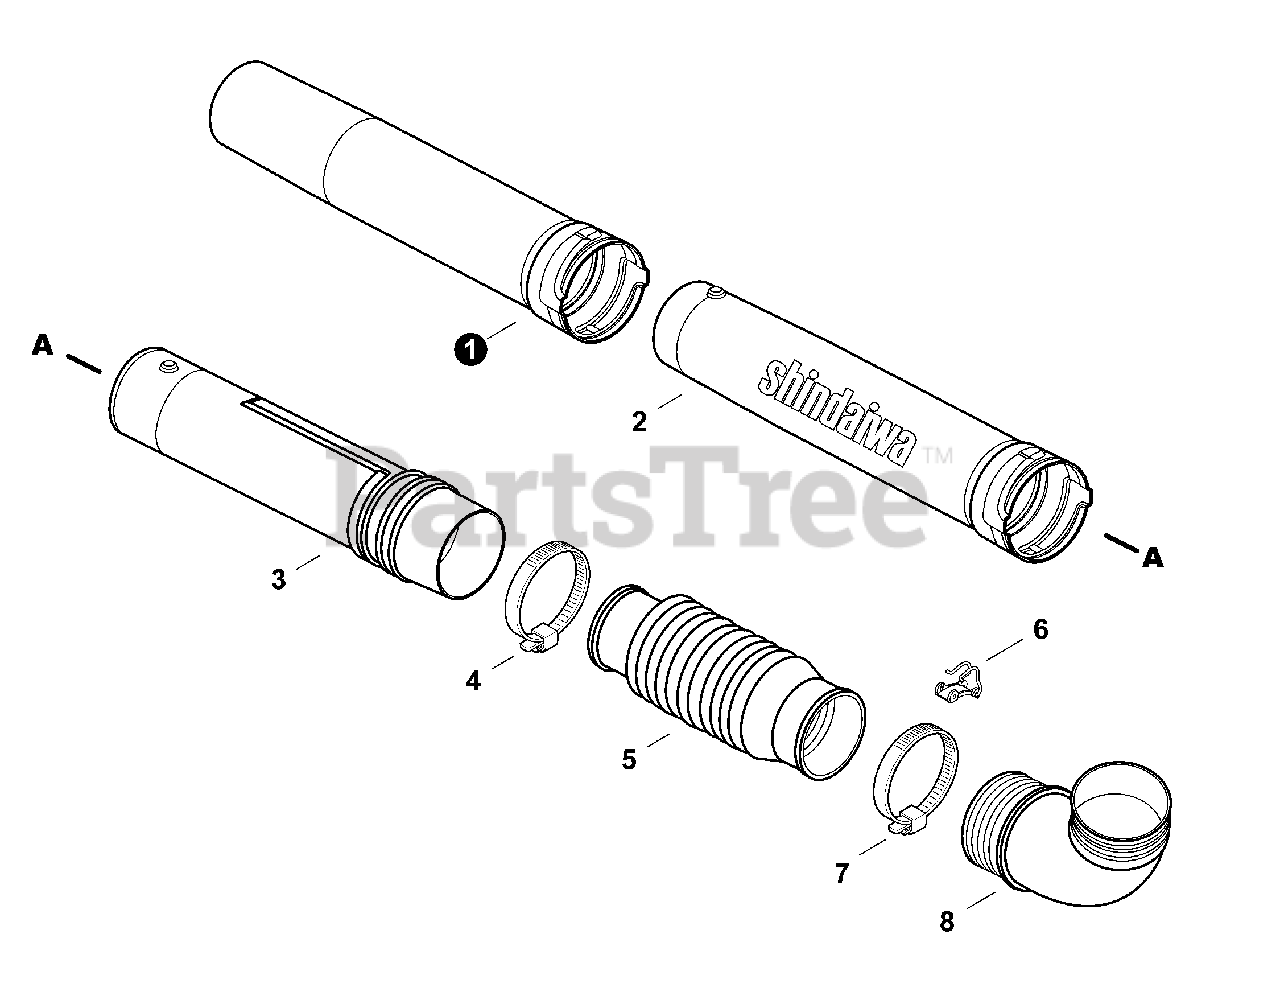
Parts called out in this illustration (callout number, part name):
1	TUBE, BLOWER - NOZZLE
2	TUBE, BLOWER - STRAIGHT
3	TUBE, BLOWER - SWIVEL
4	CLAMP 58.7MM / 82.5MM
5	TUBE, BLOWER - FLEXIBLE
6	CLIP, CABLE
7	CLAMP 77.8MM /101.6MM
8	TUBE, BLOWER - ELBOW
